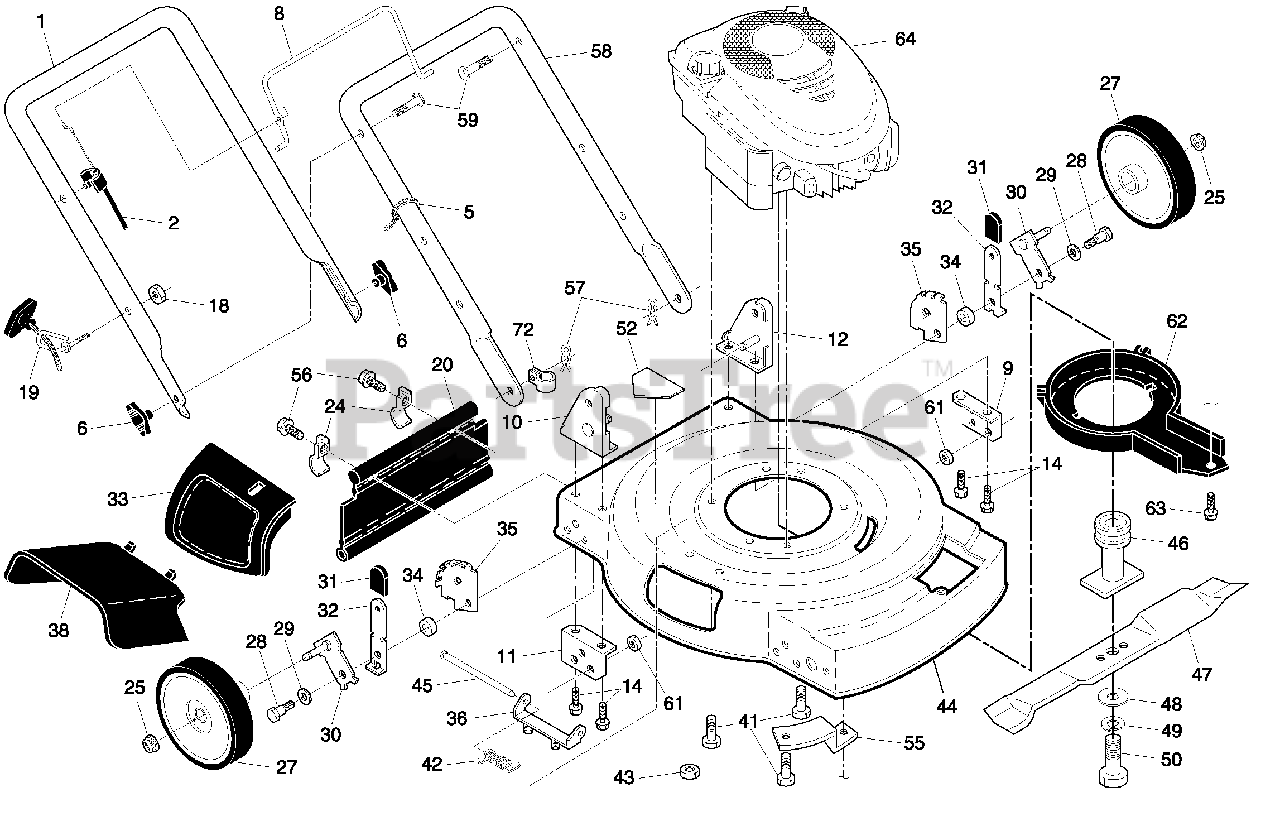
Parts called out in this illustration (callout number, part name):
1	Upper Handle
2	Engine Zone Control Cable
5	Wire Tie
6	Handle Knob
8	Control Bar
9	Support Bracket, Handle, LH
10	Handle Bracket Assembly, RH
11	Support Bracket, Handle, RH
12	Handle Bracket Assembly, LH
14	Screw, Thread Cutting 5/16-18 x 3/4
18	Locknut, Keps
19	Rope Guide
20	Rear Deflector
24	Clamp, Rear Deflector
25	Locknut, Hex 3/18-16
27	Wheel & Tire Assembly
28	Shoulder Bolt
29	Belleville Washer
30	Axle Arm Assembly
31	Knob, Selector
32	Spring, Selector
33	Discharge Guard
34	Spacer
35	Bracket, Wheel Adjuster
36	Bracket, Housing
38	Deflector, Discharge
41	Screw, Hex Head, Threaded, Rolled 3/8-16 x 1-1/8
42	Spring, Torsion
43	Locknut, Hex
44	Kit, Lawn Mower Housing
45	Rod, Hinge
46	Blade Adapter / Pulley
47	Blade, 22"
48	Washer, Hardened
49	Washer, Lock, Helical
50	Screw, Hex Head 3/8-24 x 1-3/8 Grade 8
52	Decal, Danger
55	Mounting Bracket, Debris Shield
56	Screw, Hex Washer Head #10-24 x 1/2
57	Hairpin Cotter
58	Lower Handle
59	Handle Bolt
61	Locknut, Hex
62	Debris Shield
63	Screw, Debris Shield
72	Clip, Cable
72	Operator's Manual, English
72	Operator's Manual, Spanish
72	Repair Parts Manual
72	Grass Catcher
